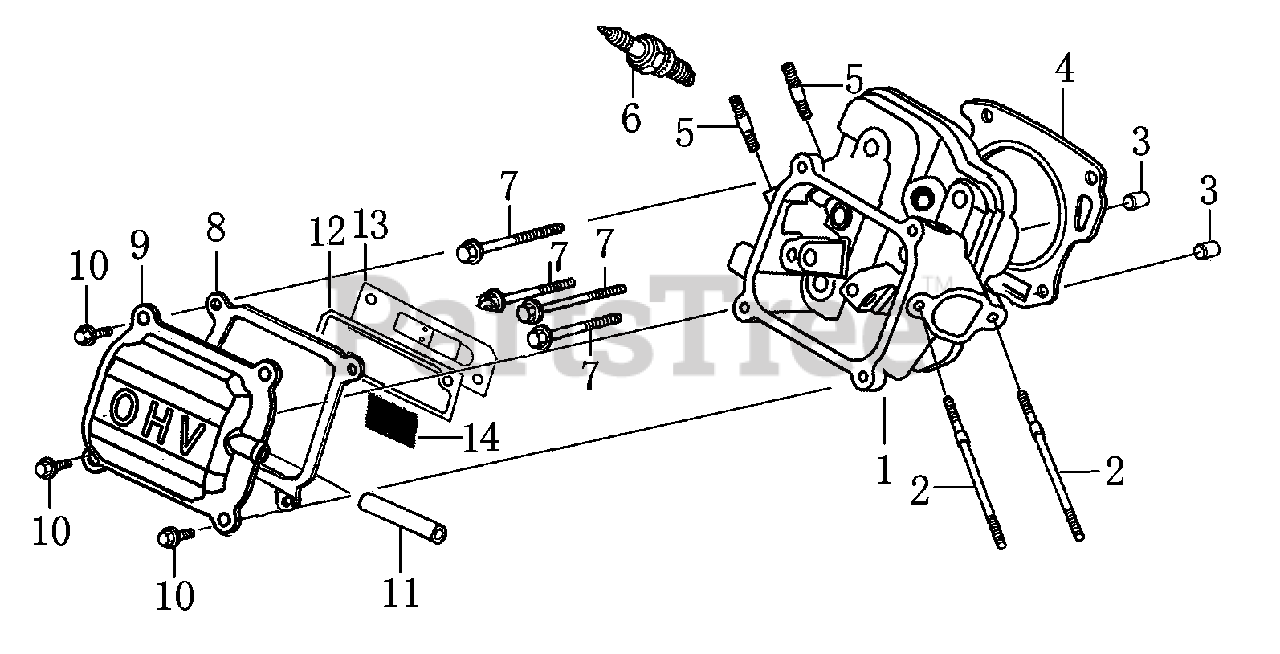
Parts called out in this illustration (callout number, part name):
1	HEAD, CYLINDER
2	BOLT, STUD,IN.
3	PIN, DOWEL
4	GASKET, HEAD CYLINDER
5	BOLT, STUD , EX.
6	PLUG, SPARK
7	BOLT, FLANGE
8	GASKET, HEAD COVER
9	COVER, HEAD
10	BOLT, FLANGE
11	TUBE, BREATHER
12	GASKET, BREATHER CHAMBER
13	CAP,BREATHER CHAMBER
14	OIL STRAINER
